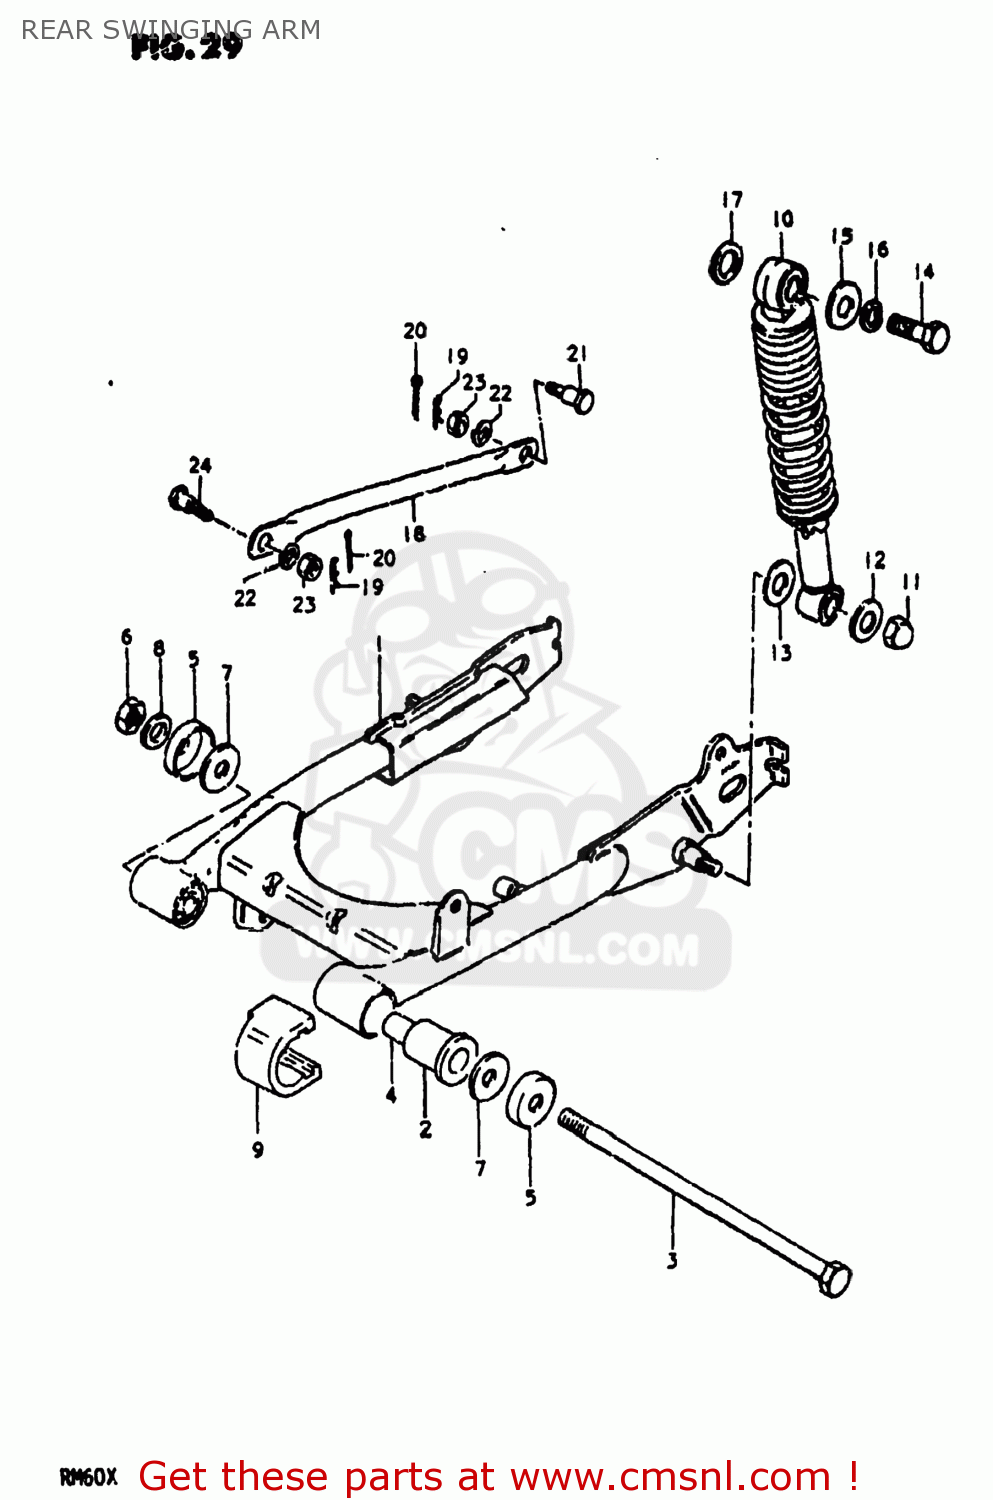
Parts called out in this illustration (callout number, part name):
1	SWING ARM ASSEMBLY,REAR
2	BUSHING
3	SHAFT, PIVOT
4	SPACER,RR SWGARM PIVOT
5	COVER,REAR SWING ARM DUST
6	NUT
7	WASHER (10.2X28X1.5)
8	WASHER
9	BUFFER,CHAIN TOUCH DEFLECTOR
10	ABSORBER ASSEMBLY,REAR SHOCK
11	NUT, LOWER LH
12	WASHER
13	WASHER
14	BOLT
15	WASHER (6.5X24X1.6)
16	LOCK WASHER
17	WASHER
18	TORQUE LINK,REAR
19	CLIP
20	COTTER PIN
21	BOLT(8X26.5)
22	LOCK WASHER
23	NUT
24	BOLT(8X22)
